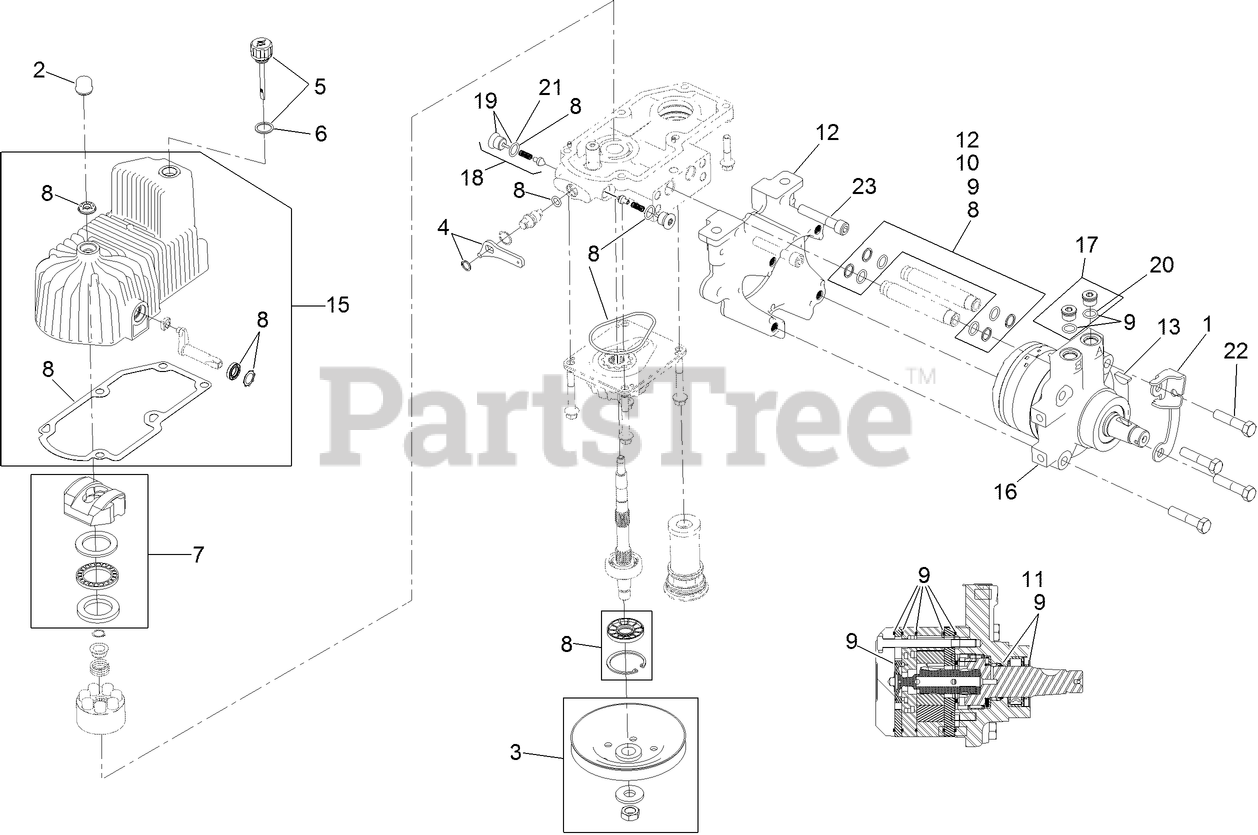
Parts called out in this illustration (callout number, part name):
1	BRACKET-ANCHOR, CABLE
2	COVER-SHAFT, HYDRO
3	PULLEY KIT
4	HANDLE-BYPASS VALVE, HYDRO
5	DIPSTICK-HYDRO W/GASKET
6	GASKET-DIPSTICK, HYDRO
7	SWASH BLOCK KIT
8	PUMP SEAL KIT
9	MOTOR SEAL KIT
10	TUBE SEAL KIT
11	OUTPUT SHAFT SEAL KIT
12	NOSE CUP-UHT
13	KEY-WOODRUFF
15	HOUSING-HYDRO, RH
16	MOTOR-HYDRAULIC RH 240CC
17	MAGNETIC PLUGS SERVICE KIT
18	CHECK VALVE ASM
19	PLUG-CHECK (W/O-RING)
20	O-RING
21	O-RING-CHECK VALVE
22	SCREW HH
23	SCREW-HSH
